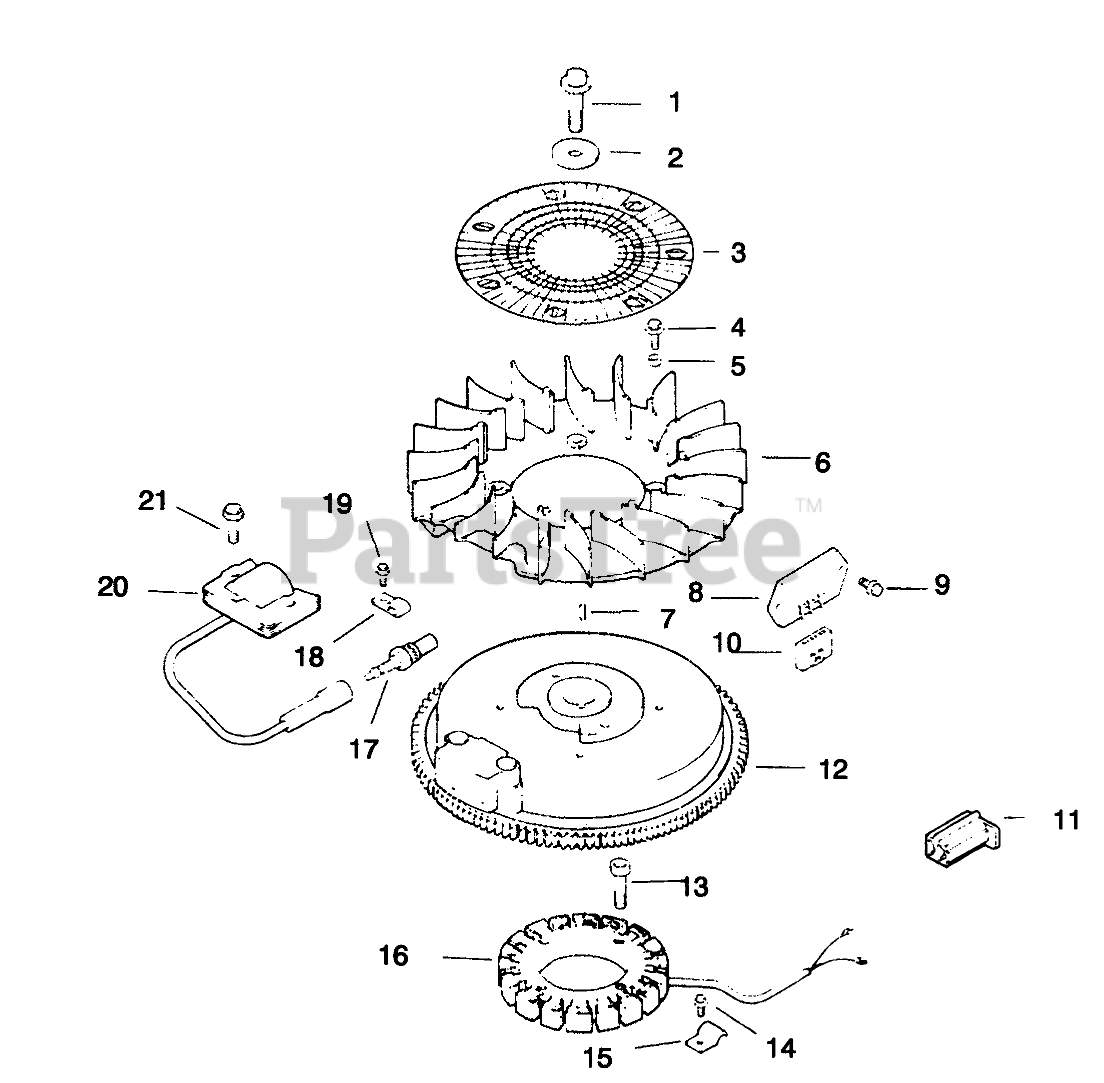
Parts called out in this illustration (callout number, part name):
1	Screw
2	Washer-Flat
3	Screen-Grass
4	Screw
5	Spacer
6	Fan
7	Key
8	Rectifier-Unregulated
9	Screw
10	Connector
11	Connector
12	Flywheel ASM
13	Screw
14	Screw
15	Clip-Stator Harness
16	Stator-15 Amp
17	Plug-Spark
18	Clip
19	Screw
20	Module-Ignition
21	Screw
